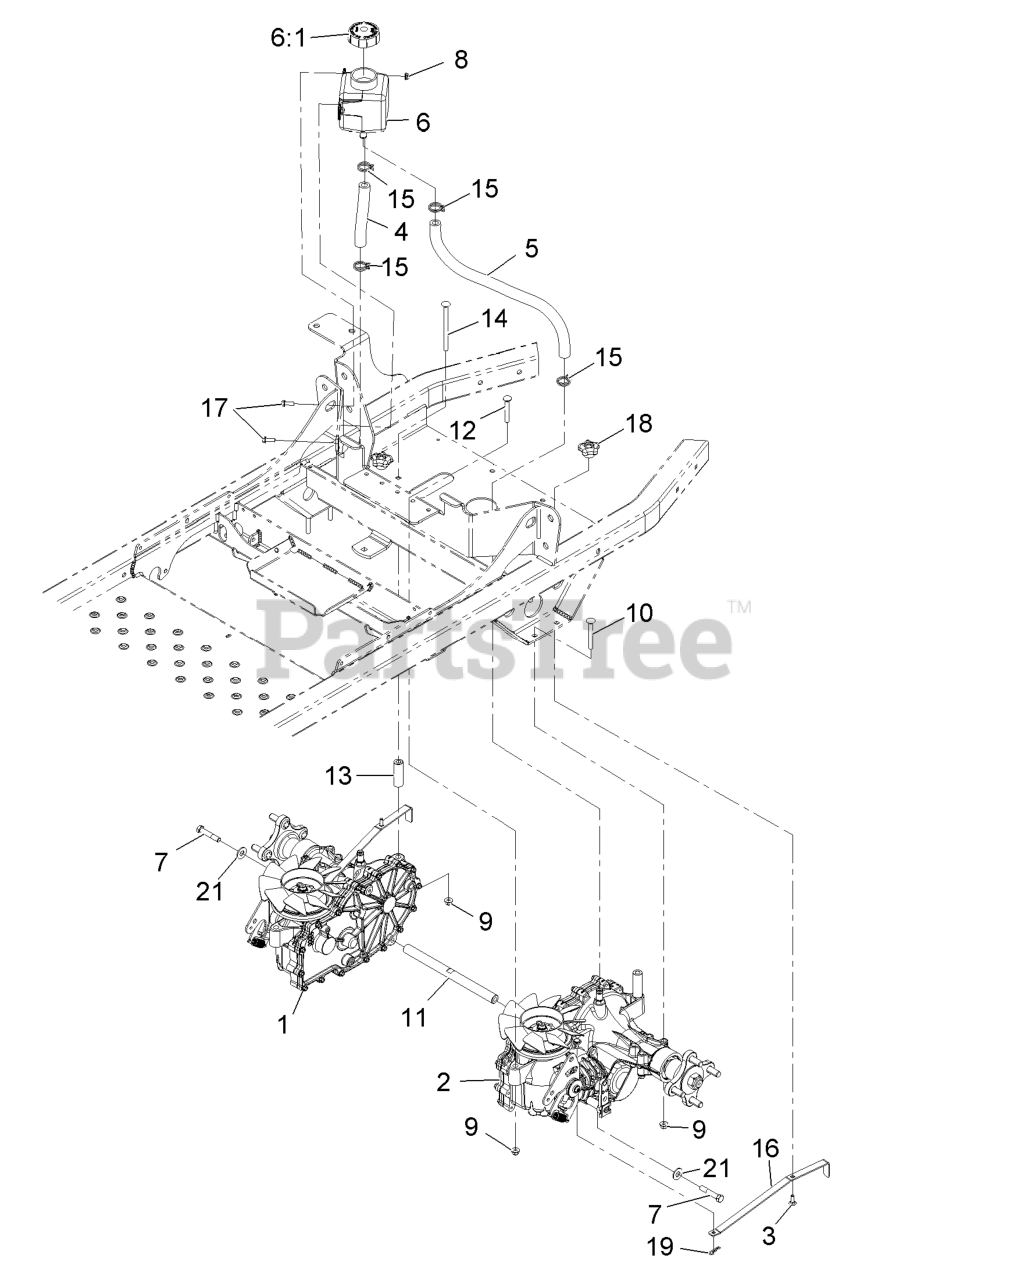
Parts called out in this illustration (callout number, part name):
1	TRANSAXLE ASM
2	TRANSAXLE ASM
3	BOLT-CARR
4	HOSE-HYDRAULIC
5	HOSE-HYDRAULIC
6	TANK-HYD
6:1	CAP-RESERVOIR, HYD
7	SCREW-HH W/LOCTITE
9	NUT-HF, NI
10	SCREW-CARR
11	SHAFT-TRANSAXLE SPACER
12	BOLT-CARR
13	SPACER-HYDRO
14	Bolt-Carriage 5/16-18 X 1 1/4
15	CLAMP-HOSE
16	ARM-BYPASS, HYDRO
17	SCREW-HWH
18	KNOB-HANDLE
19	PIN-COTTER
21	WASHER-FLAT
